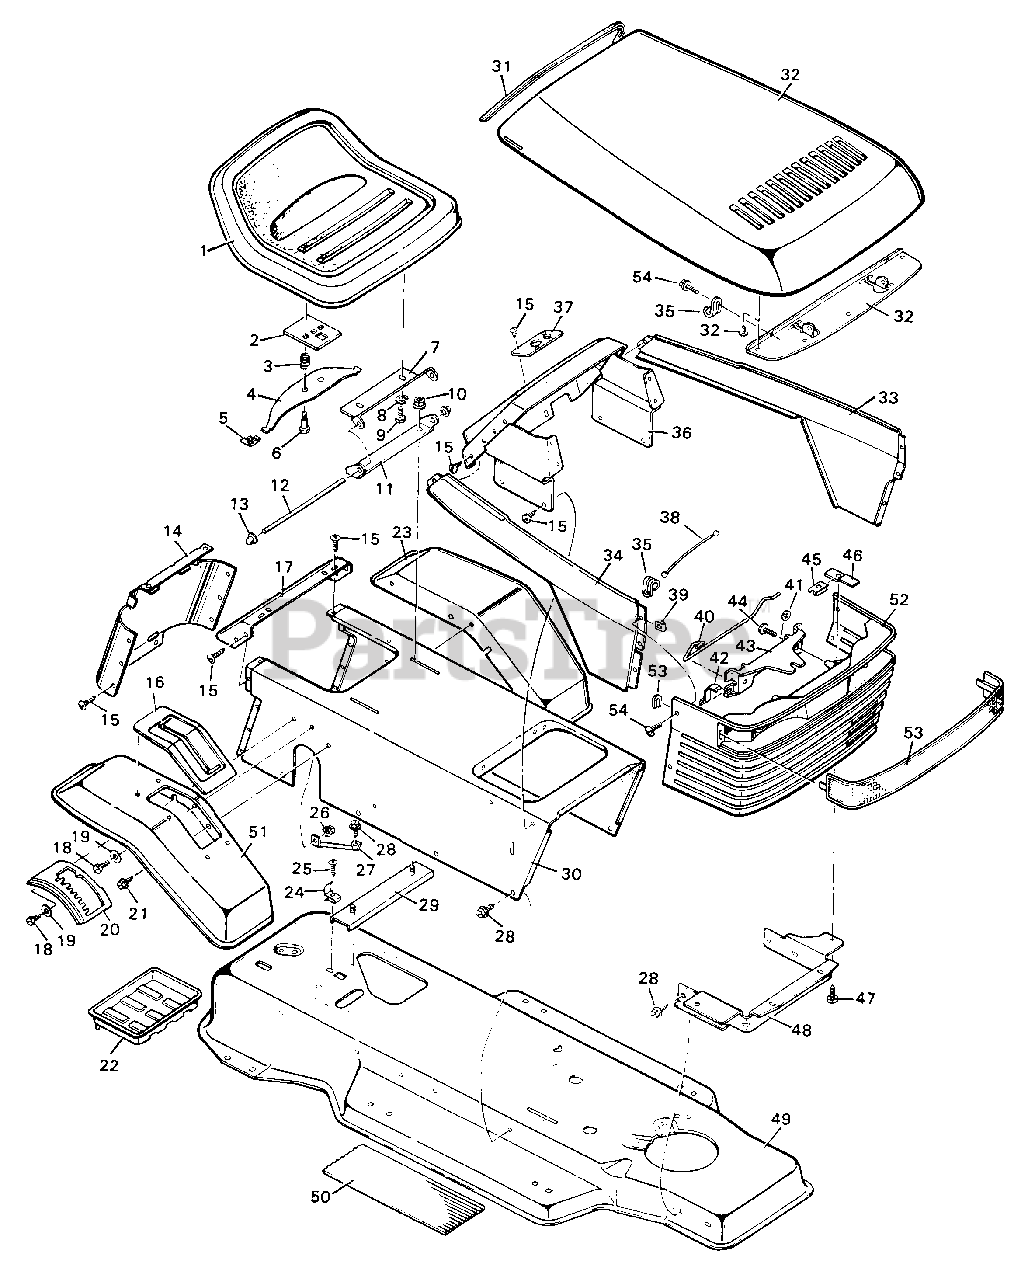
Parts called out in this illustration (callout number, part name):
2	SWITCH PLATE ASSEMBLY
3	SPRING- Compression
4	SPRING- Seat
5	GLIDE- Spring
6	BOLT- Shoulder
7	SUPPORT- Seat
8	WASHER- Lock (5/16)
9	BOLT- Hex
10	NUT- Hex washer
11	BRACKET- Pivot
12	ROD- Pivot
13	CAP- Push on
14	CAP- Console
15	SCREW- Tap
16	COVER- Shift
17	FENDER- Apron
18	BOLT- Hex
19	WASHER- Flat
20	GATE- Shift
22	TRAY- Battery
23	FENDER- Left
24	CLIP- Battery
26	NUT- Lock
27	STRUT- Console
29	CHANNEL ASSEMBLY
31	TRIM- Edge
32	HOOD ASSEMBLY
33	PANEL- Left
34	PANEL- Right
35	CLIP- Cable
36	DASH ASSEMBLY
39	U-FASTENER
40	ROD- Hinge
41	WASHER
42	SPRING- Hood
43	BRACKET- Hood mount
45	NUT- Speed
46	SHIELD- Heat
48	SUPPORT- Grille
51	FENDER- Right
